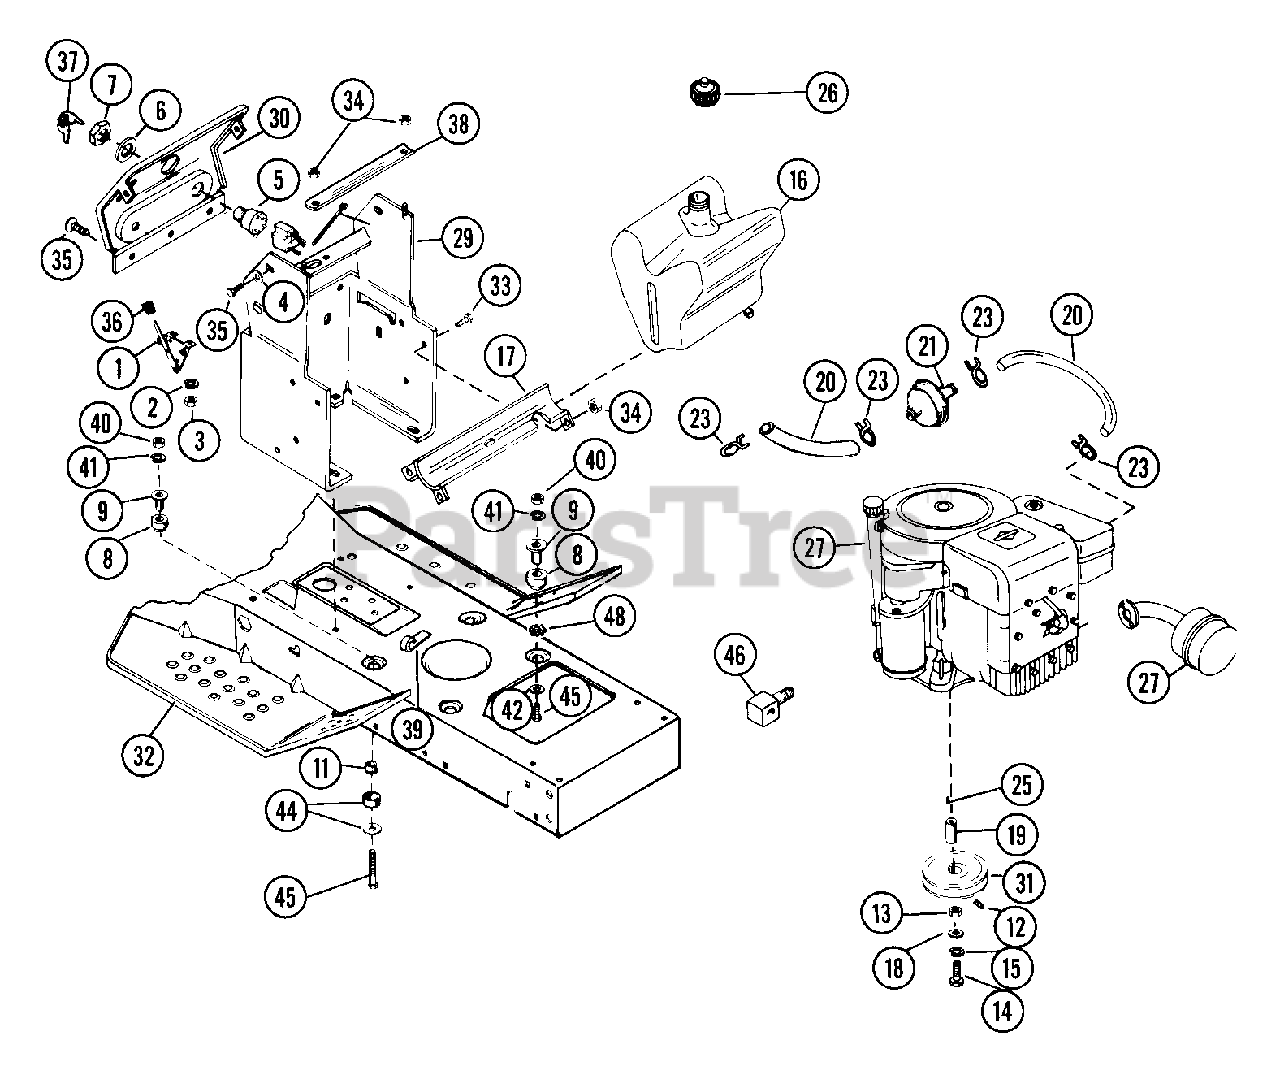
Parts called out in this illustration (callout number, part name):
1	THROTTLE CONTROL
2	WSHR-LK 10X.047 MED PL
3	NUT-HEX 10-24 PL
4	WSHR-FL-STL .250X.562X.049 PL
5	IGNITION SWITCH
6	WSHR-LK-INT .563X.040 PL
7	NUT .562-24
8	BOTTOM ISOLATION MOUNT
9	SPACER-SHOULDER
11	RUBBER BUSHING
12	SCR-SET .32-18X.25 SKHCUP OH
13	SPACER 1.032X1.250X.312
14	BLT-HEX .44-20X1.00 GR5
15	WSHR-LK .438X.133 HVY
16	FUEL TANK
17	LOWER TANK SUPPORT
18	WSHR-FL-STL .469X1.380X.125
19	BEARING SPACER 1.032X1.25X1.78
20	HOSE (SERV. ONLY)
21	FUEL FILTER
23	CLAMP-HOSE WIR.490/.510X.092#8
24	TIE DOWN
25	KEY-SQ .25X1.0X.25 SAE 8630
26	GAS CAP
27	EXHAUST MUFFLER
29	DASH BASE WITH DECALS
30	DASH
31	PLY-? 3.50X1.0
32	FRAME W/DECALS
33	BLT-HEX .25-20X.50 PL GR2
34	NUT-LK TOP .250-20 PL
35	SCR-SHT.MET10-16X.375 HWH PL B
37	KEYS
38	CLAMP STRAP
39	J-CLAMP
40	NUT-HEX .312-18
41	WSHR-LK .312X.097 PL HVY
42	WSHR-FL-STL .312X1.62X.13
44	TOP ISOLATION MOUNT
45	BLT-HEX .31-18X2.50 PL GR2
46	PIPE FITTING 90 DEG. X 3/8 ELB
47	BLT-HEX .31-18X.75 PL GR2
48	WSHR-LK-EXT .313X.030 PL
